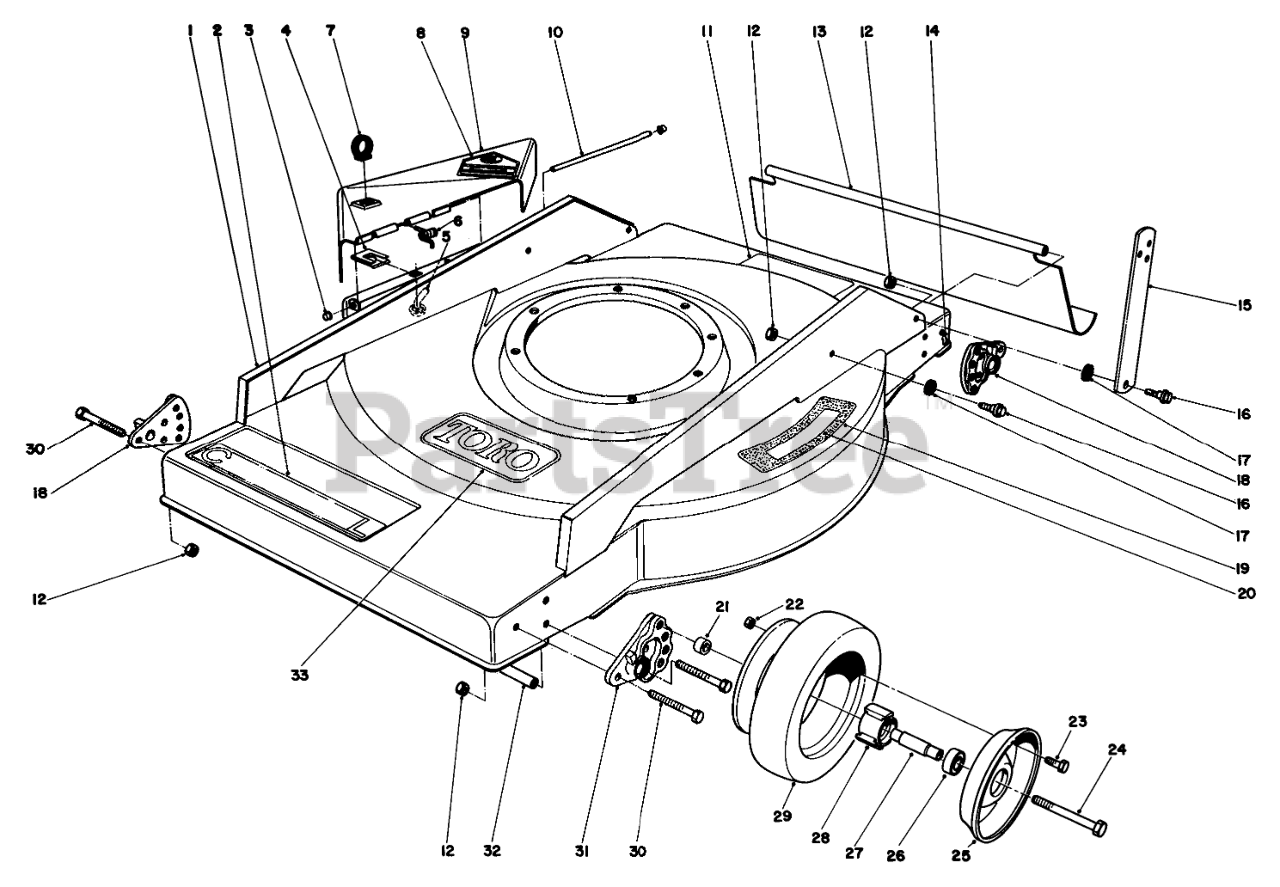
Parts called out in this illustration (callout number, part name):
1	Housing (Incl. Ref. #2, 19 & 20)
2	COMMERCIAL DECAL
3	PUSHNUT-CAP, WASHER
4	BAG CHUTE CLIP PIN
5	BAG CHUTE PIN
6	TORSION SPRING
7	LIFT LOOP
8	DECAL-DANGER
9	Deflector (Incl. Ref. #8)
10	DEFLECTOR PIVOT ROD
11	DECAL SAF INST
12	NUT-LOCK, NI
13	REAR SAFETY SHIELD
14	SHIELD ROD
15	Handle Strap
16	SCREW-SHOULDER
17	HANDLE LATCH SPACER
18	WHL QUADRANT B-MACH.
19	PAD STEP
20	Decal Step Pad
21	SPACER-WHEEL
22	NUT-LOCK, NI
23	SCREW-HHF
24	SCREW-HH
25	Wheel-Half
26	BEARING-WHEEL
27	SPACER-BEARING
28	HUB-BEARING
30	SCREW-HH
31	WHL QUADRANT A-MACH.
32	Rod-Tie
33	Decal Tow
